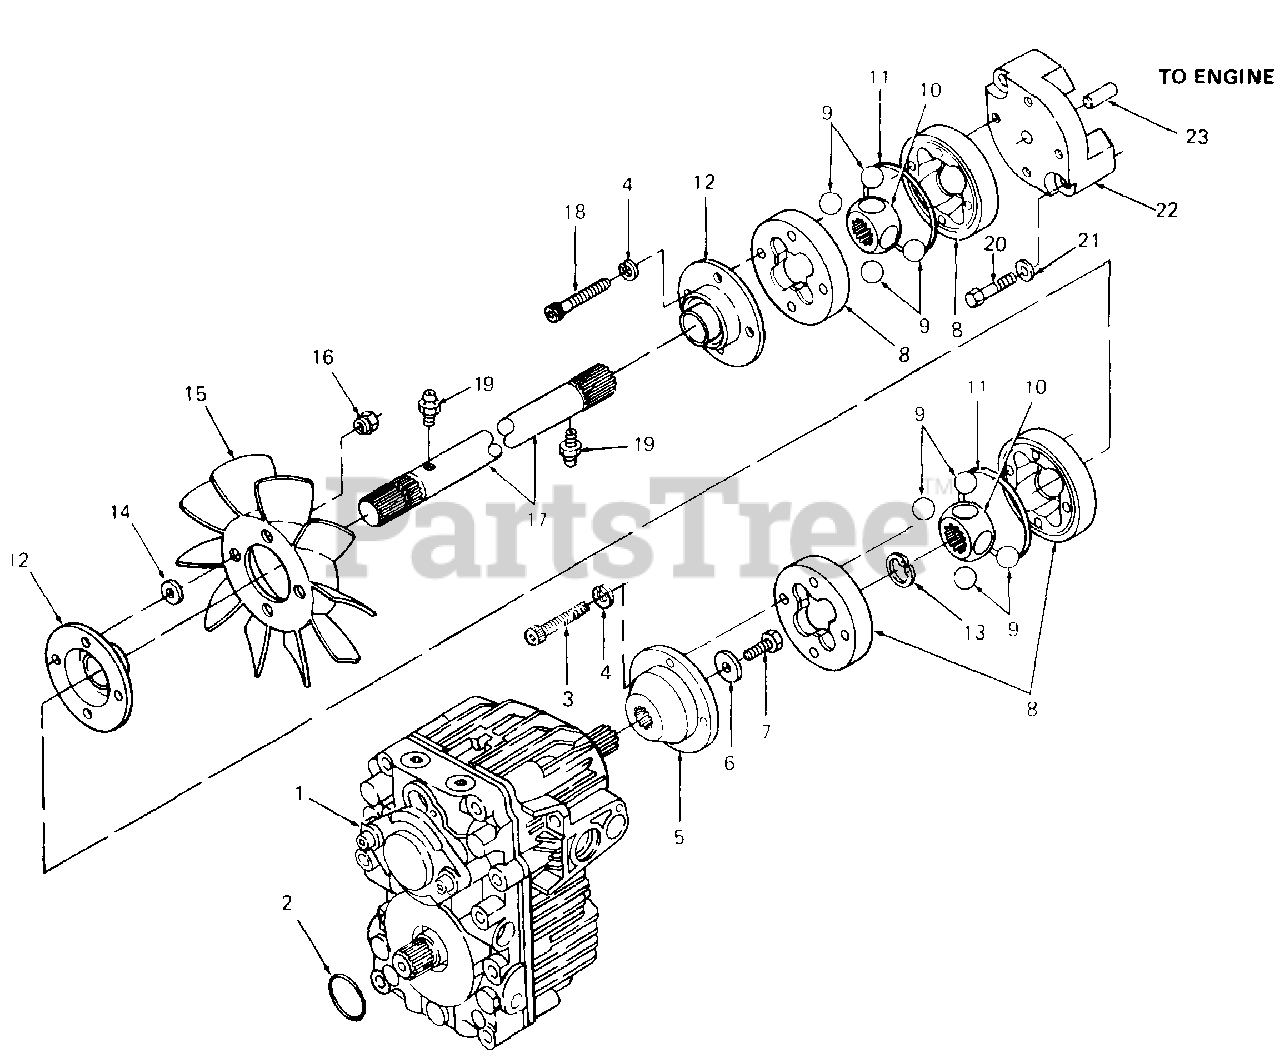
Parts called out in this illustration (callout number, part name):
1	Pump, Hydrostatic
2	O-Ring, 2.75 ID X .103 Dia
3	Screw, Socket Hd Cap, 1/4-20 X 2.0 Lg
4	Washer, Lock, 1/4
5	Adapter, Pump
6	Washer, Bell, .265 X .75 X .062 Thk
7	Bolt, Hex Patch, M6-1.0 X 20 MM Lg GR10.9
8	Coupling, Drive w/0-Ring Groove
9	Ball, Steel, 5/8 Dia Chrome
10	Hub, Drive
11	O-Ring, 2.489 X .070
12	Boot, Coupling
13	Ring, Snap
14	Washer, Flat, .25 X .62 X .052 Thk
15	Fan, 10 Blade Hydro
16	Nut, Fan, 1/4-20
17	Shaft, Drive, 21.3 Lg
18	Screw, Socket Hd Cap, 1/4-20 X 1.75 Lg
19	Fitting, Grease
20	Screw, Hex Cap, 5/16-18 X 1.75 Lg GR5
21	Washer, Flat, .312 X .750 X .119 Thk
22	Adapter, Drive Shaft
23	Pin, Locating
